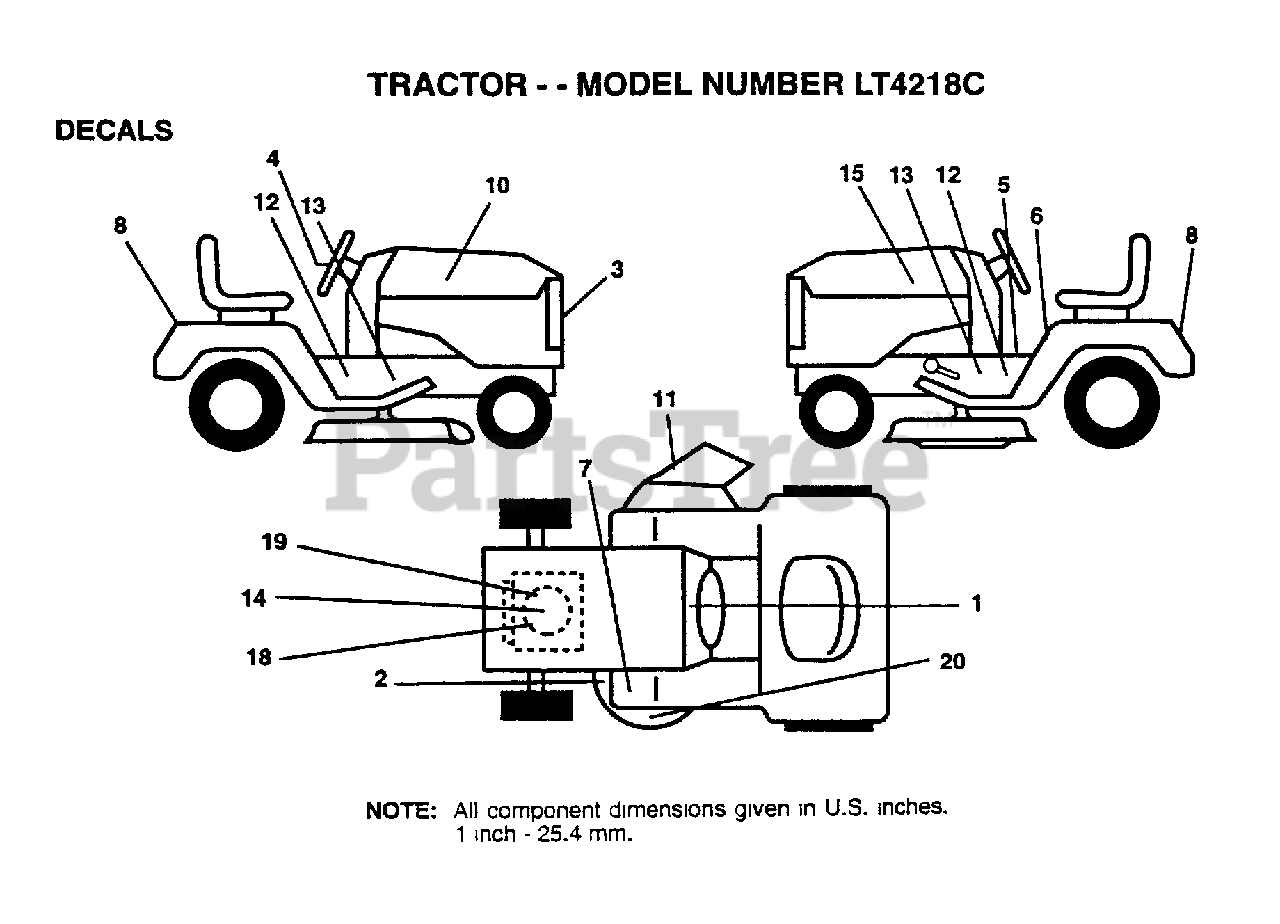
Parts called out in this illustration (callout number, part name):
1	DECAL INST OP DAS
2	DECAL
3	DECAL LOGO GRILLE
4	DECAL.INST.WHL.ST
5	DECAL BRAK PARK
6	DECAL CAUT FEND
7	DECAL CLUT/BRAKE
8	DECAL FEND QUICK
10	DECAL HD RH
11	DECAL DANGER CT/F
12	DECAL CHASSIS KGR
14	DECAL.ENG.272757
15	DECAL HD LH
18	DECAL.ENG.272101
20	DECAL DECK MULCH
